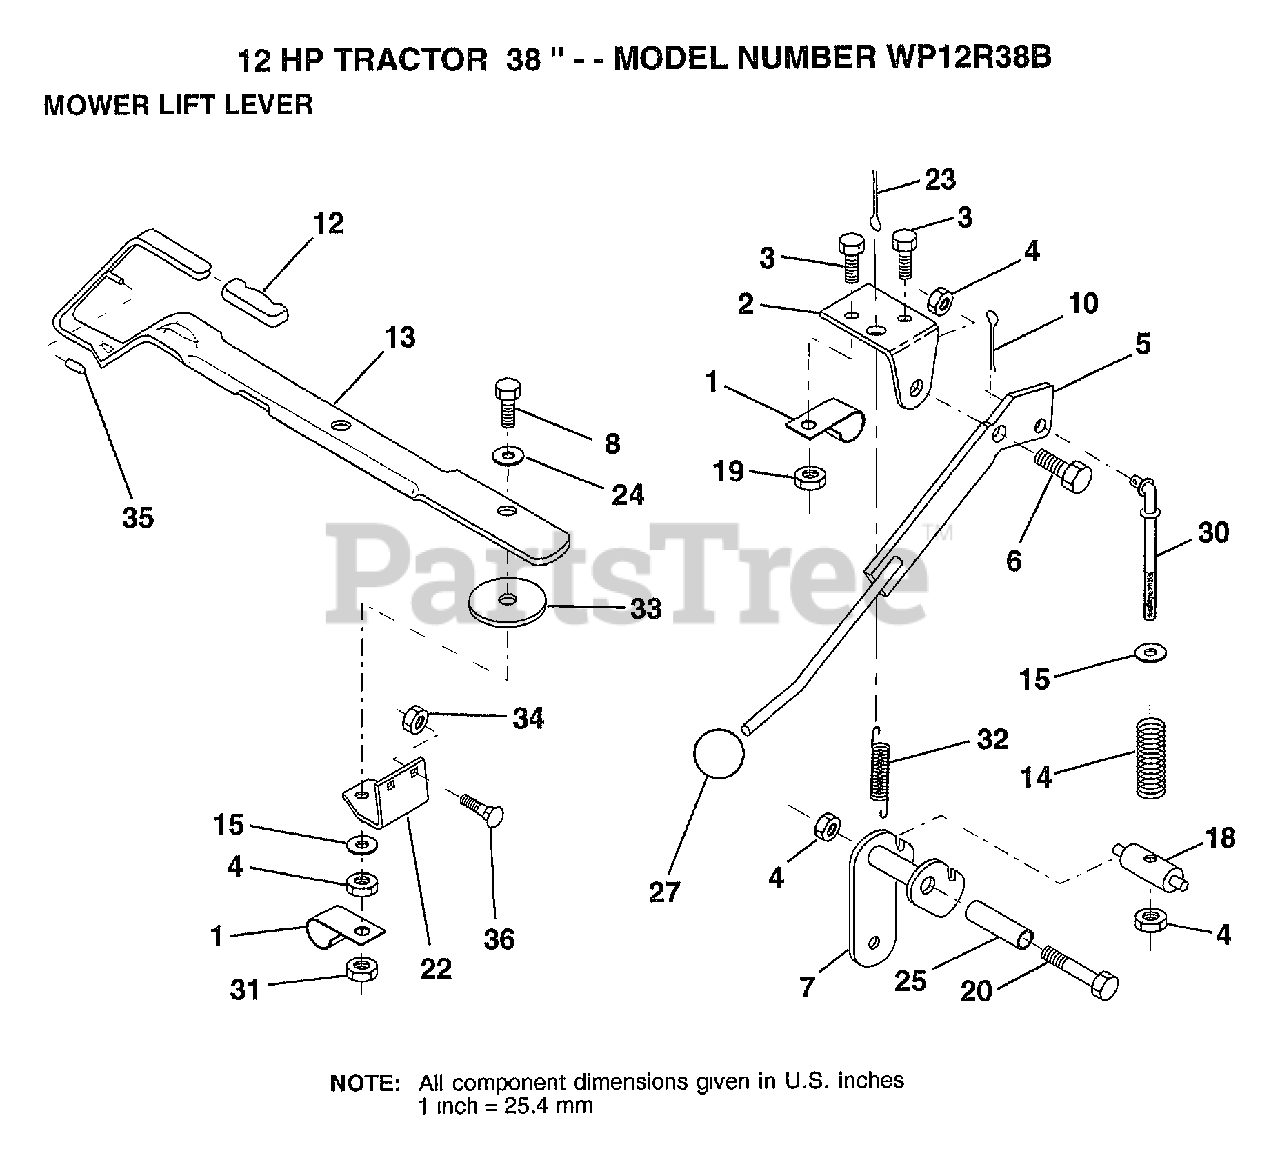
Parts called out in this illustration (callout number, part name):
1	"CLIP,INSULATOR"
2	BRKT CLUTCH
3	BOLT
5	CLUTCH LEVER AS
6	"BOLT, SHOULDER LT"
7	MWR CLUT ARM ASM
8	BOLT
10	COTTER PIN
12	GRIP HANDLE
13	LEVER LIFT LR
14	COMP CLUTCH SPRNG
15	WASHER HYT
18	TRUNNION
20	BOLT
22	LIFT LEVER BRKT
24	WASHER
25	TUBE SPACER
27	KNOB
30	ROD TENSION CLUTC
31	LOCKNUT
32	SPRING EXT
33	WASHER
35	VINYL CAP RED
36	BOLT
